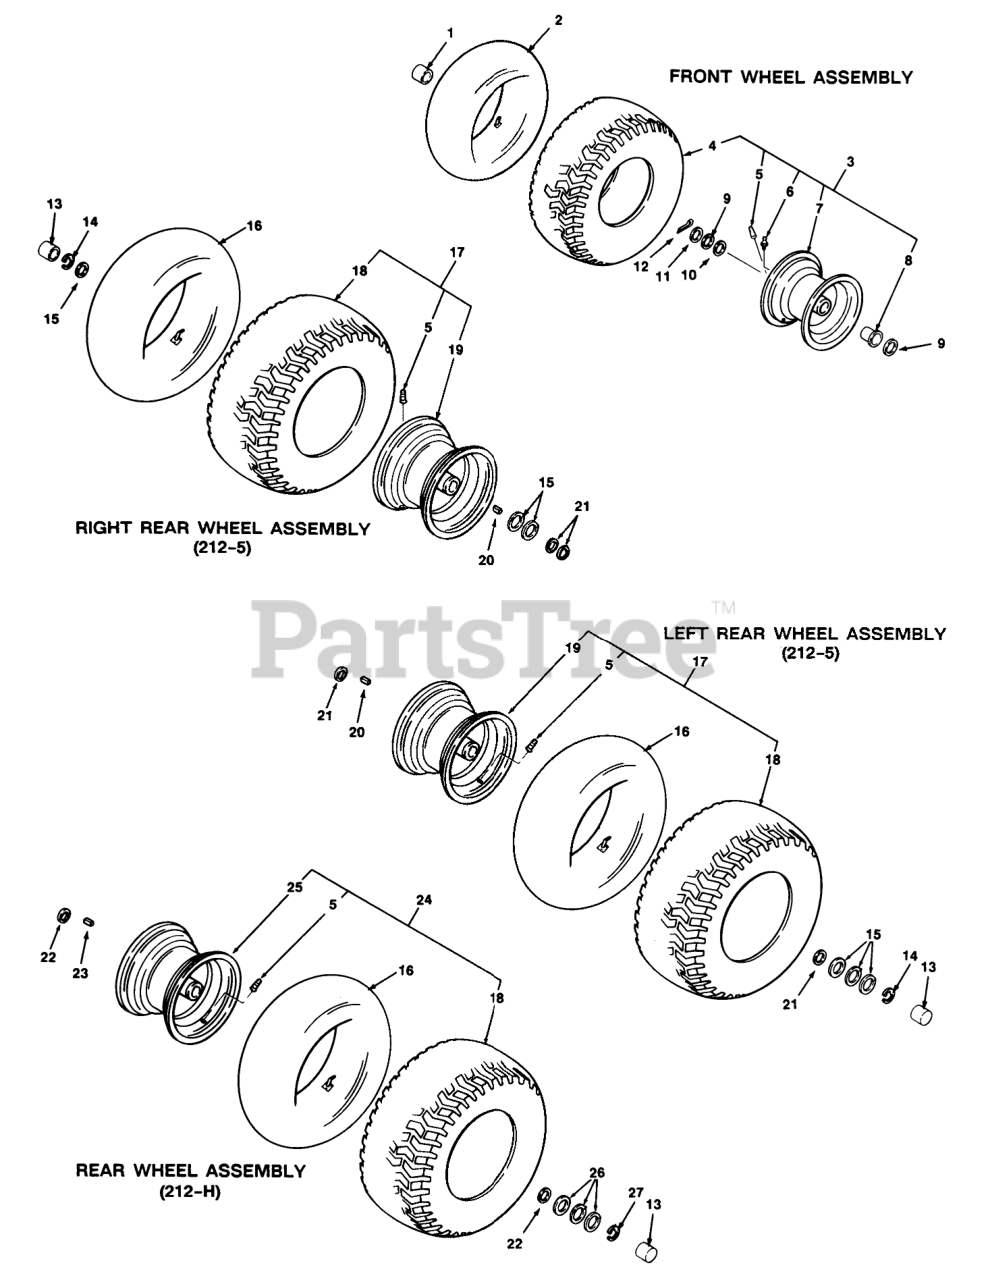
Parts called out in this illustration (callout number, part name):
1	HUB CAP-FLAT BLACK
3	Front Wheel & Tire Assy. (Incl. Ref. #4-8)
4	TIRE-15 X 6.00-6
5	VALVE
6	ZERK-GREASE
7	Front Wheel Assembly (Incl. Ref. #5, 6 & 8)
8	Bearing
9	WASHER
10	WASHER-SHIM
11	WASHER-FLAT
12	PIN-COTTER
13	HUB CAP
14	E-RING
15	WASHER-FLAT
16	Tube-Inner
17	Rear Wheel & Tire Assy. (Incl. Ref. #5, 18 & 19)
18	TIRE-18X9.50-8 TT RS
19	Rear Wheel Assembly (Incl. Ref. #5)
20	SQ KEY
21	WASHER
23	KEY-SQUARE
24	Rear Wheel & Tire Assy. (Incl. Ref. #5, 16 & 25)
25	Rear Wheel Assembly (Incl. Ref. #5)
26	WASHER-WHEEL
27	RING-RETAINING
